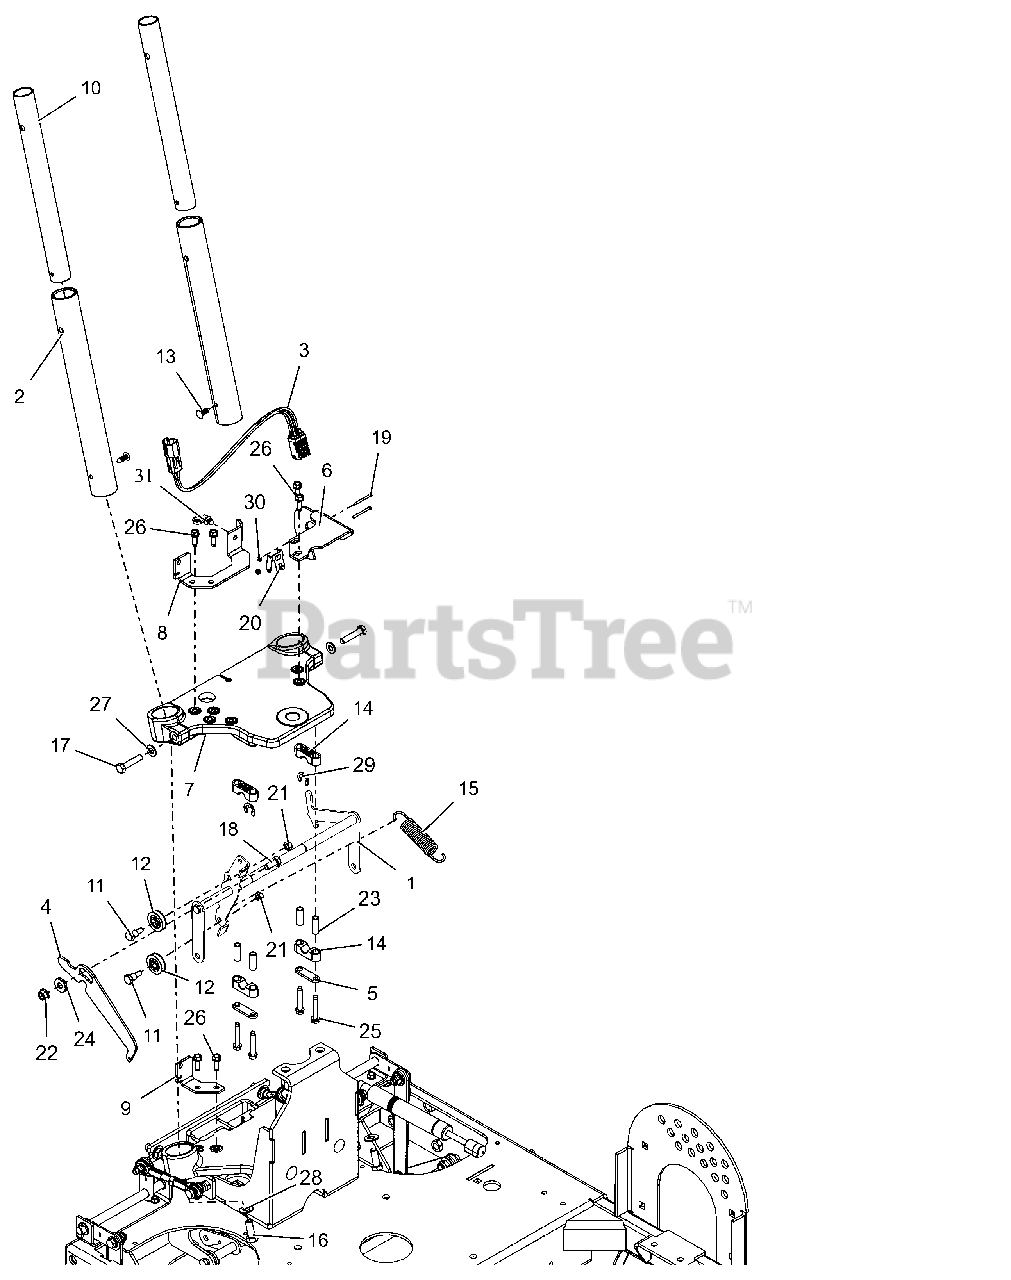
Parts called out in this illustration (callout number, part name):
1	WLDMT, UPPER STEERING SHAFT
2	WLDMT, STEERING TUBE
3	HARNESS, NEUTRAL HYDRO PRO WALK
4	BRKT, RTN
5	PLATE, BEARING SUPPORT (BLACK)
6	BRKT, LH CONTACT SWITCH (RED)
7	BRKT, UPPER STEERING
8	BRKT, CABLE MTG
9	BRKT, CABLE MTG (RED)
10	BUSHING, SLV
11	BOLT, SHLDR-.375X.375X.25-20
12	PULLEY, CABLE
13	RIVET, .25 NYLON PANEL
14	BSHG, STEERING SHAFT
15	SG-TENS .105X.812X3.88 WLD 15
16	@BLT-HEX .38-16X1.00 GR5 YWZC
17	@BLT-HEX .31-18X1.50 GR5 YWZC
18	@BLT-HEX .31-18X.75 GR5 YWZC
19	SCR-SKH 4-40 X 1.25
20	ACTUATOR, SWITCH
21	@NUT-HEX .25-20 YWZC
22	@NUT-LK-TOP-FLG .31-18 YWZC
23	BSHG-SLV .277X.375X1.00
24	BSHG-FLG .325X.499X.3X.875
25	@SCR-TAP .25-20X1.50 HWH TR YZ
26	SCR-TAP-PM .25-20X.75 TR YWZ
27	@WSHR-FL-STL.344X.688X.065YWZC
28	@WSHR-FL-STL.406X.812X.065 YWZ
29	RG-RTNG-EXT .500X.042 (E)
30	NUT, LK-NYL #4-40 GR5 ZC120
31	CABLE TIE W/ TREE (.25 HOLE)
